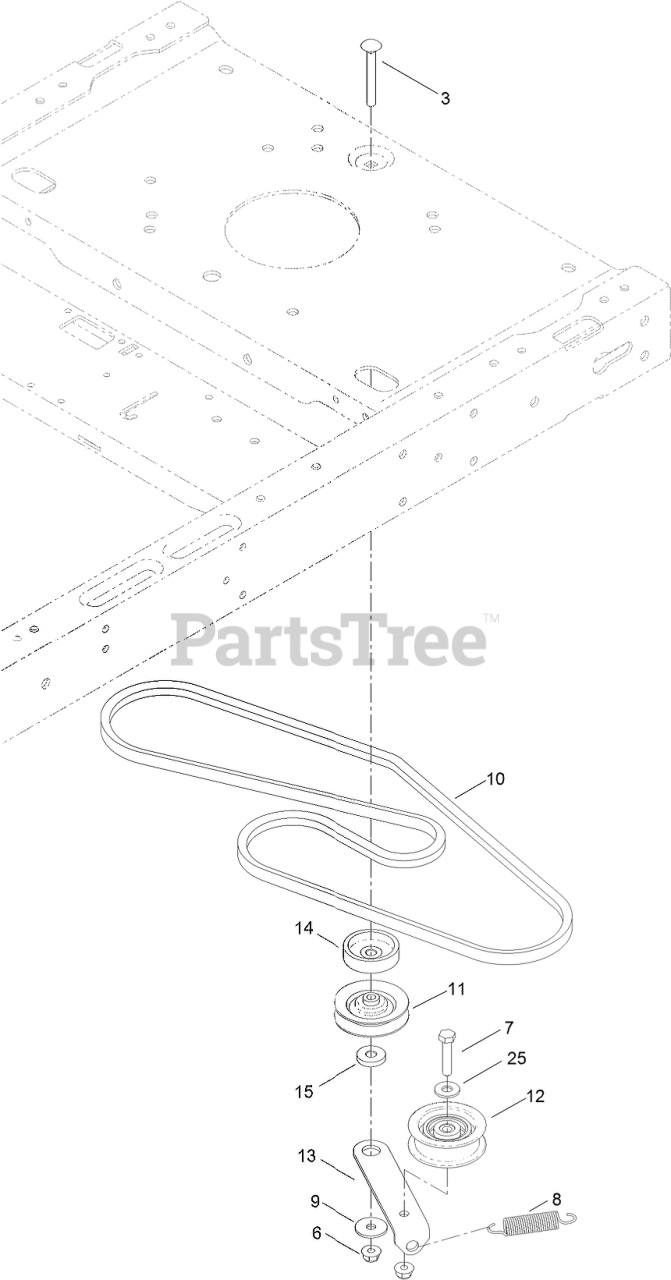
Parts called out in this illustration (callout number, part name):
3	SCREW-CARR
6	NUT-HF, NI
7	SCREW-HH
8	SPRING-RETURN, PEDAL
9	WASHER-PIVOT
10	V-BELT
11	PULLEY-IDLER
12	PULLEY-IDLER
13	ARM-IDLER
14	SPACER
15	SPACER-ARM, IDLER
25	WASHER-FLAT
